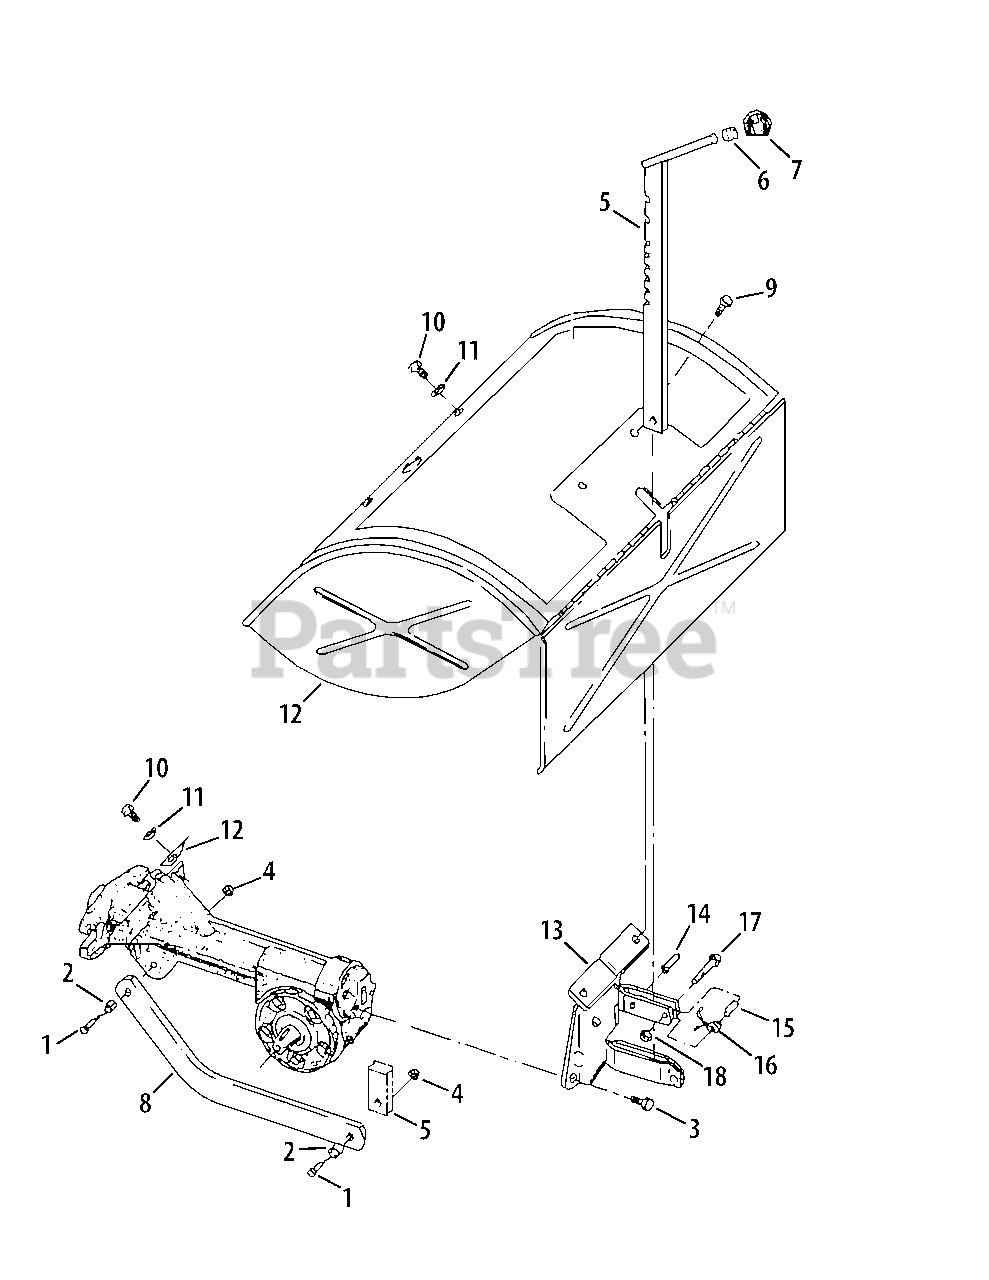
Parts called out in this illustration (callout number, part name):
1	Hex Bolt, 3/8"-16 x 1-1/4"
2	Bushing Spacer, .5 x .375 x .3
3	Hex Flange Bolt, 5/16"-18 x .625
4	Flangelock Nut, 3/8"-16
5	Depth Regulator
6	Retaining Ring
7	Depth Regulator Knob
8	Depth Regulator Bar Drag
9	Thread-forming Screw, 1/4"-20 x 1/2"
10	Hex Flange Bolt, 5/16"-18
11	Washer, 1.12 x .34 x .06
13	Hood Bracket
14	Roll Pin (Spirol), 1/4" x 1"
15	Split Spacer
17	Hex Bolt, 1/4"-20 x 1"
18	Locknut, 1/4"-20
